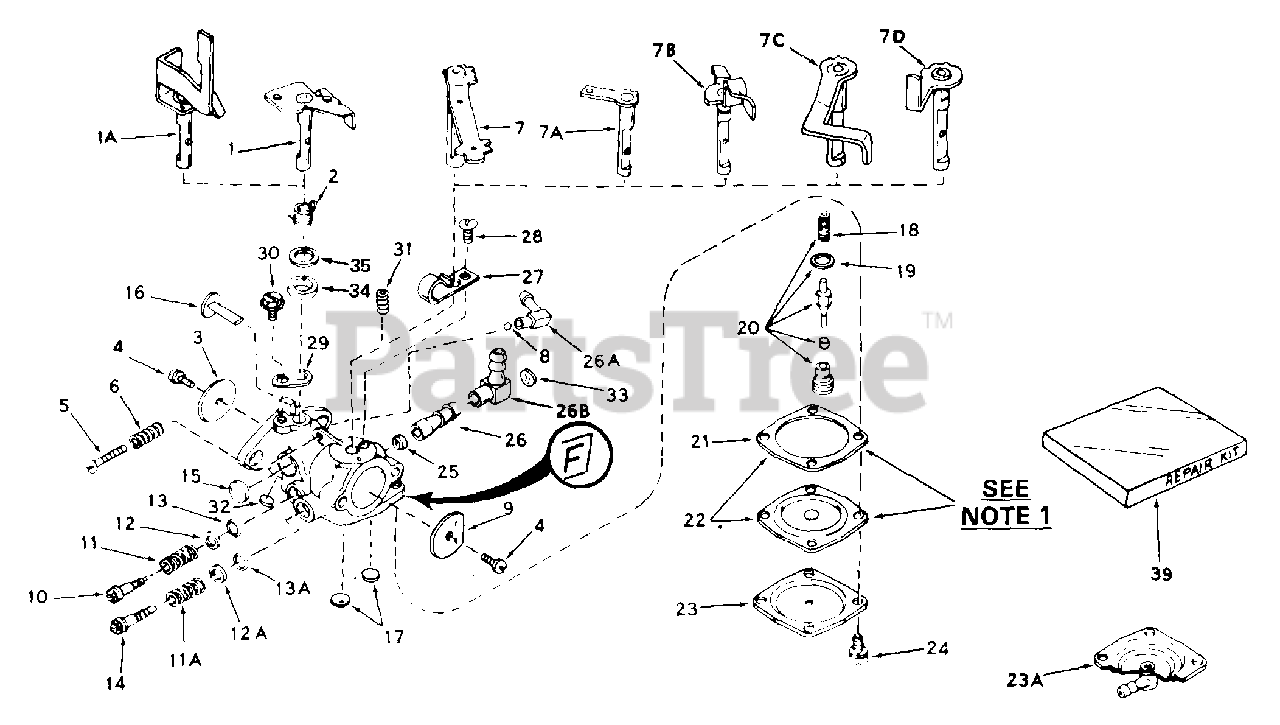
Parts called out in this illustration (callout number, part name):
1A	"Shaft & Lever Assy., Throttle
2	Spring, Throttle return
3	Shutter, Throttle
4	Screw, Throttle & Choke shutter
5	Screw, Idle regulating
6	Spring, Idle Regulating Screw
7C	Shaft & Lever Assy., Choke
9	Shutter, Choke
10	Screw, Idle adj
11	Spring, Adj. screw
11A	Spring, Adj. screw
12	Washer, Adj. screw
12A	Washer, Adj. screw
13	"O" Ring, Adj. screw
13A	"O" Ring, Adj. screw
14	Screw, Main adj
15	Plug, Welch
17	Plug, Welch
18	Spring, Valve
19	Gasket, Valve seat
20	Inlet Needle, Seat, Gasket & Spring A ssy.
21	Gasket, Diaphragm
22	Diaphragm Assy.
23	Cover, Diaphragm
24	Screw, Cover
26B	Fitting, Fuel inlet
29	Retainer, Throttle shaft
31	Spring, Choke positioning
39	Repair Kit
